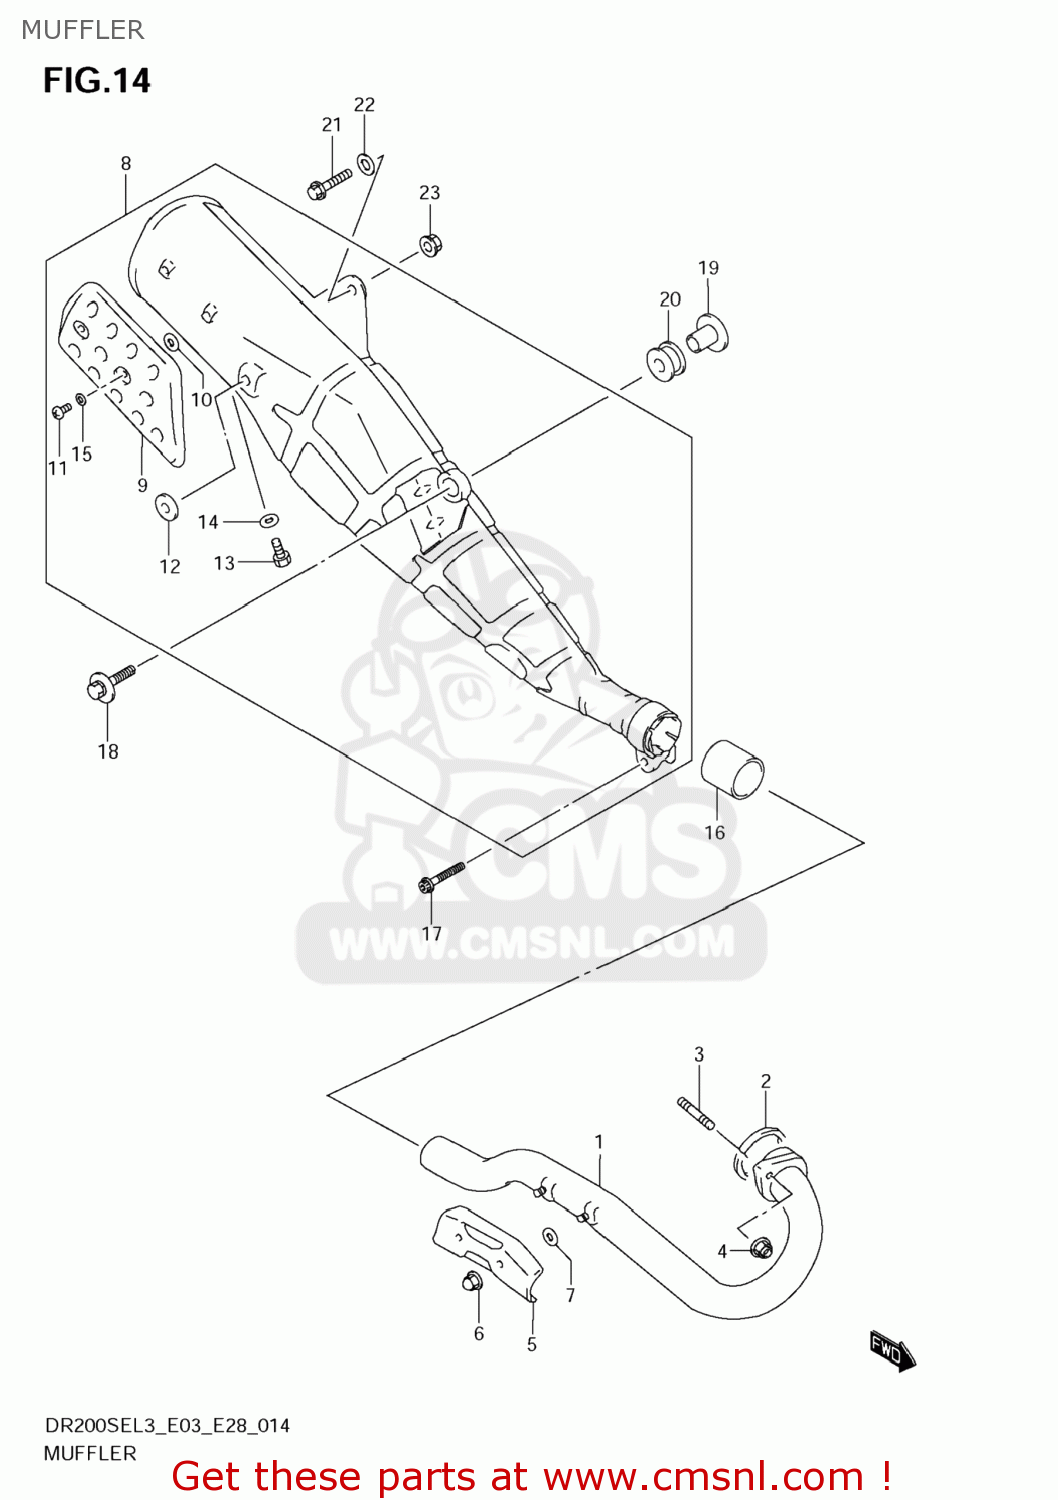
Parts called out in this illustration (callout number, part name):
1	PIPE,EXHAUST
2	GASKET,EXHAUST PIPE (NAS)
3	BOLT,STUD
4	NUT
5	COVER,EXHAUST PIPE
6	NUT
7	GASKET(6X16X1.4) (NAS)
8	MUFFLER ASSY
9	COVER,MUFFLER
10	GASKET(5.8X13X1.4) (NAS)
11	SCREW(6X10)
12	CUSHION
13	PLUG(12X9)
14	GASKET(12.1X16.2X3.7) (NAS)
15	WASHER
16	GASKET,2ND MUFFLER (NAS)
17	BOLT
18	BOLT(8X35)
19	SPACER(8.6X12X17.5)
20	CUSHION
21	BOLT(8X35)
22	WASHER
23	NUT
